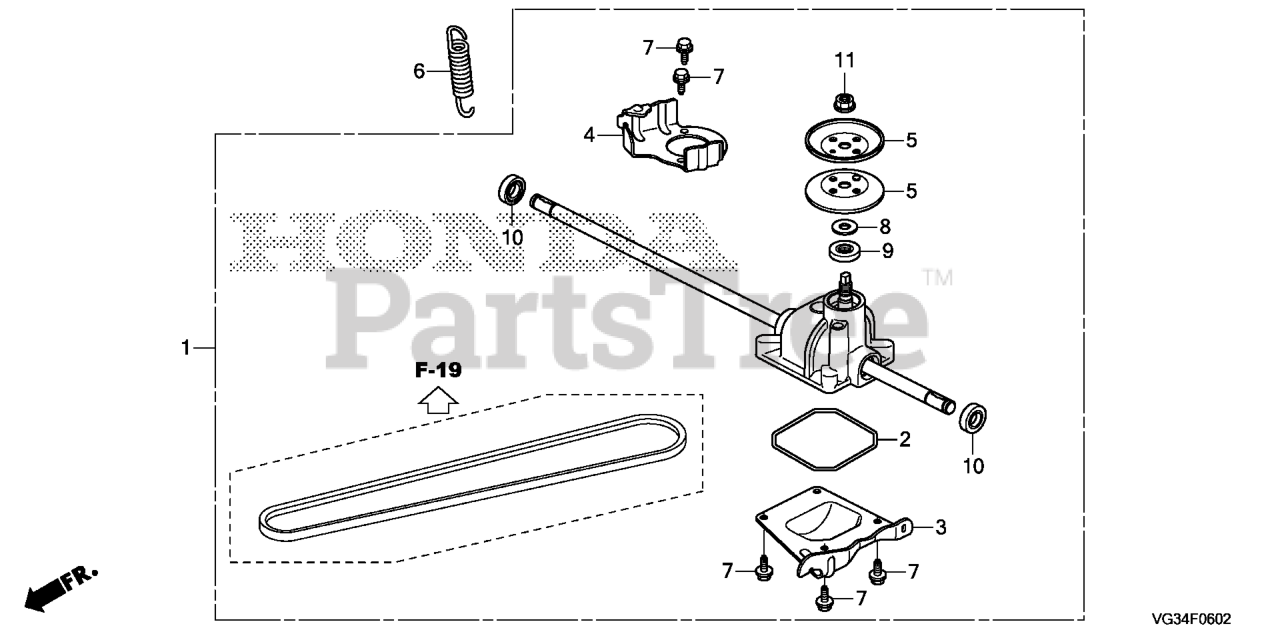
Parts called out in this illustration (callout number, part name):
1	TRANSMISSION ASSY.
2	O-RING, CASE
3	COVER, REDUCTION
4	GUIDE, BELT
5	FACE, DRIVEN
7	BOLT, FLANGE (6X12) (CT200)
8	WASHER (10X24)
9	OIL SEAL (12.7X28.6X6.4)
10	OIL SEAL (12.7X22.2X6.4)
11	NUT, FLANGE (10MM)
